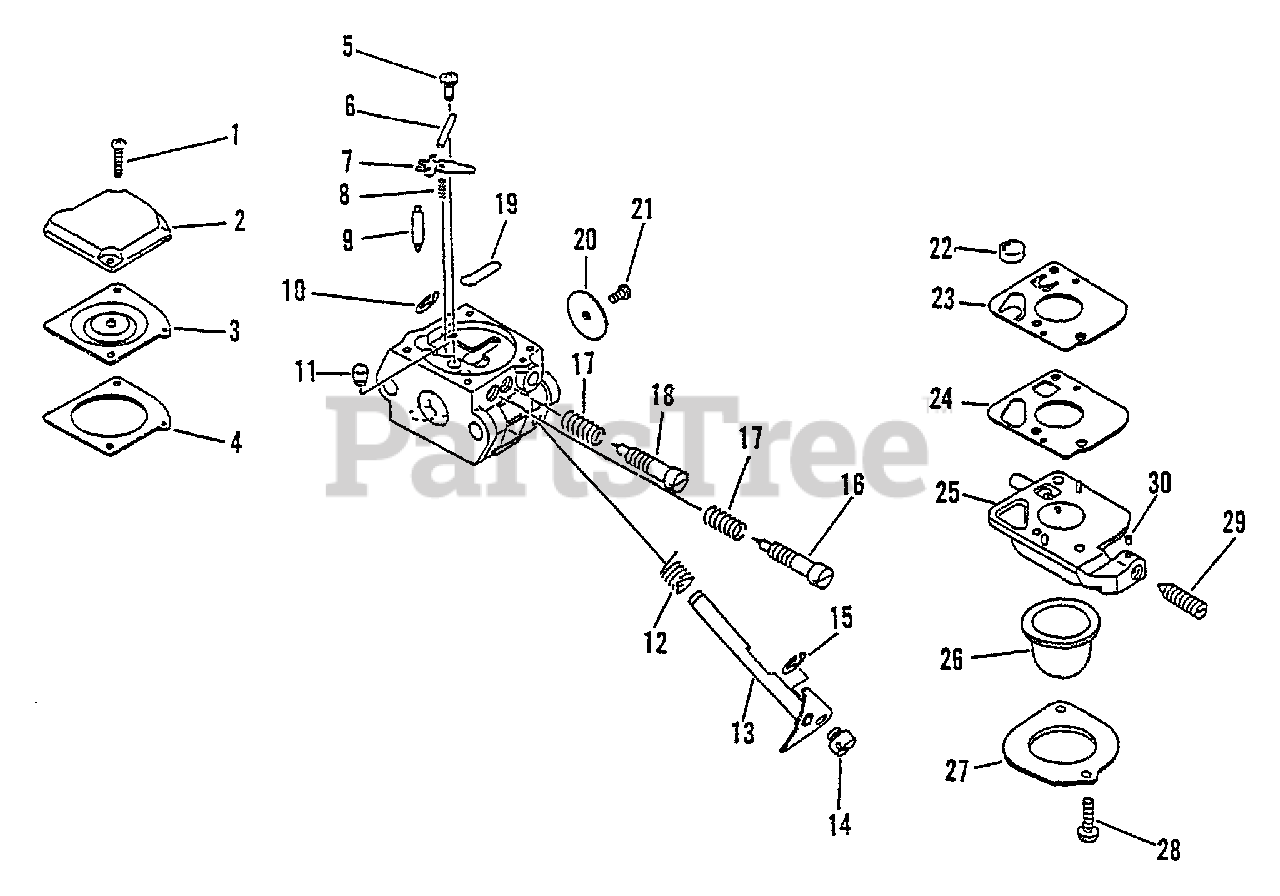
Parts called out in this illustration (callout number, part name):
2	COVER, METERING
3	DIAPHRAGM
4	GASKET, METERING
5	SCREW
6	PIN
7	LEVER, METERING
8	SPRING
9	VALVE, NEEDLE
10	RING, RETAINING
11	NOZZLE, CHECK VALVE
12	SPRING, RETURN
13	SHAFT, THROTTLE
15	RING, RETAINING
16	NEEDLE - LOW SPEED
18	NEEDLE - HIGH SPEED
19	PLUG, WELCH
20	VALVE, THROTTLE
22	STRAINER
23	DIAPHRAGM, PURGE
24	GASKET, PURGE
25	BASE, PURGE
26	BULB, PURGE
27	RETAINER, PURGE BULB
28	SCREW, RETAINER
29	SCREW, IDLE ADJUST
30	PIECE, FRICTION
